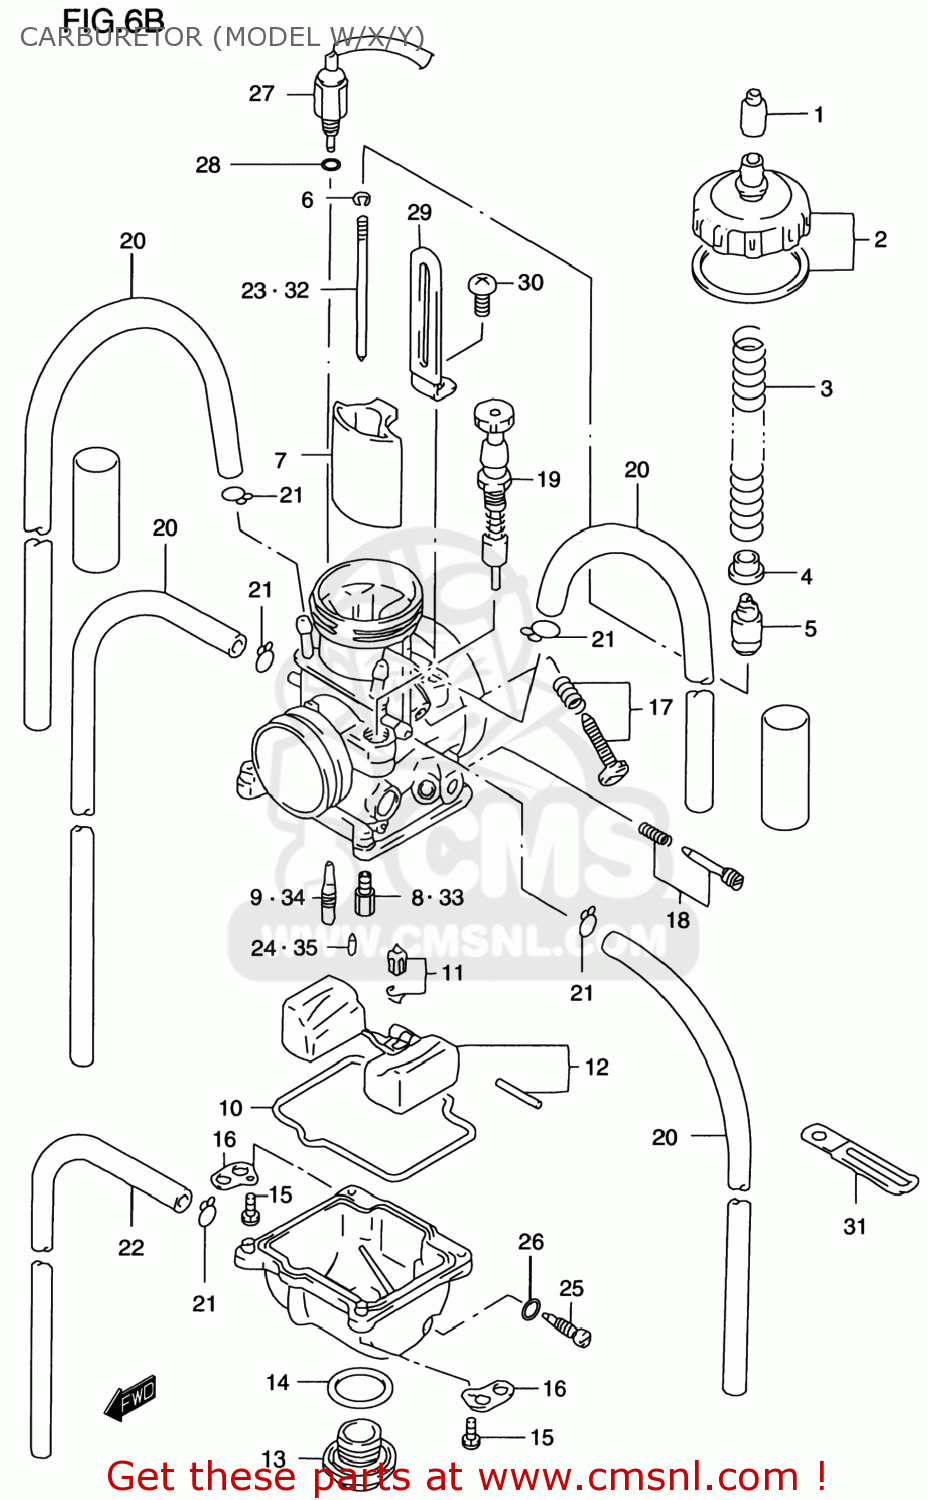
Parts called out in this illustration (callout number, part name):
1	CAP,CARBURETOR
2	CAP SET,TOP
3	SPRING,THROTTLE VALVE
4	COLLAR,THROTTLE VALVE
5	HOLDER,CABLE
6	CLIP,NEEDLE
7	VALVE,THROTTLE
8	JET,MAIN(162)
9	JET,SLOW(42)
10	GASKET,FLOAT CAHMBER
11	VALVE SET,FLOAT
12	FLOAT SET
13	BOLT,DRAIN
14	O RING
15	SCREW
16	PLATE
17	SCREW SET,STOP
18	SCREW SET,AIR
19	STARTER VALVE
20	HOSE(4X7X620)
21	CLIP
22	HOSE(3.5X6.5X600)
23	NEEDLE(N1EI)
24	JET,POWER(60)
25	SCREW,DRAIN
26	O RING
27	SOLENOID ASSY
28	O RING
29	CLAMP
30	SCREW
31	CLAMP(L:45)
32	NEEDLE(N0ZG)
33	JET,MAIN(150)
34	JET,SLOW(35)
35	JET,POWER(50)
